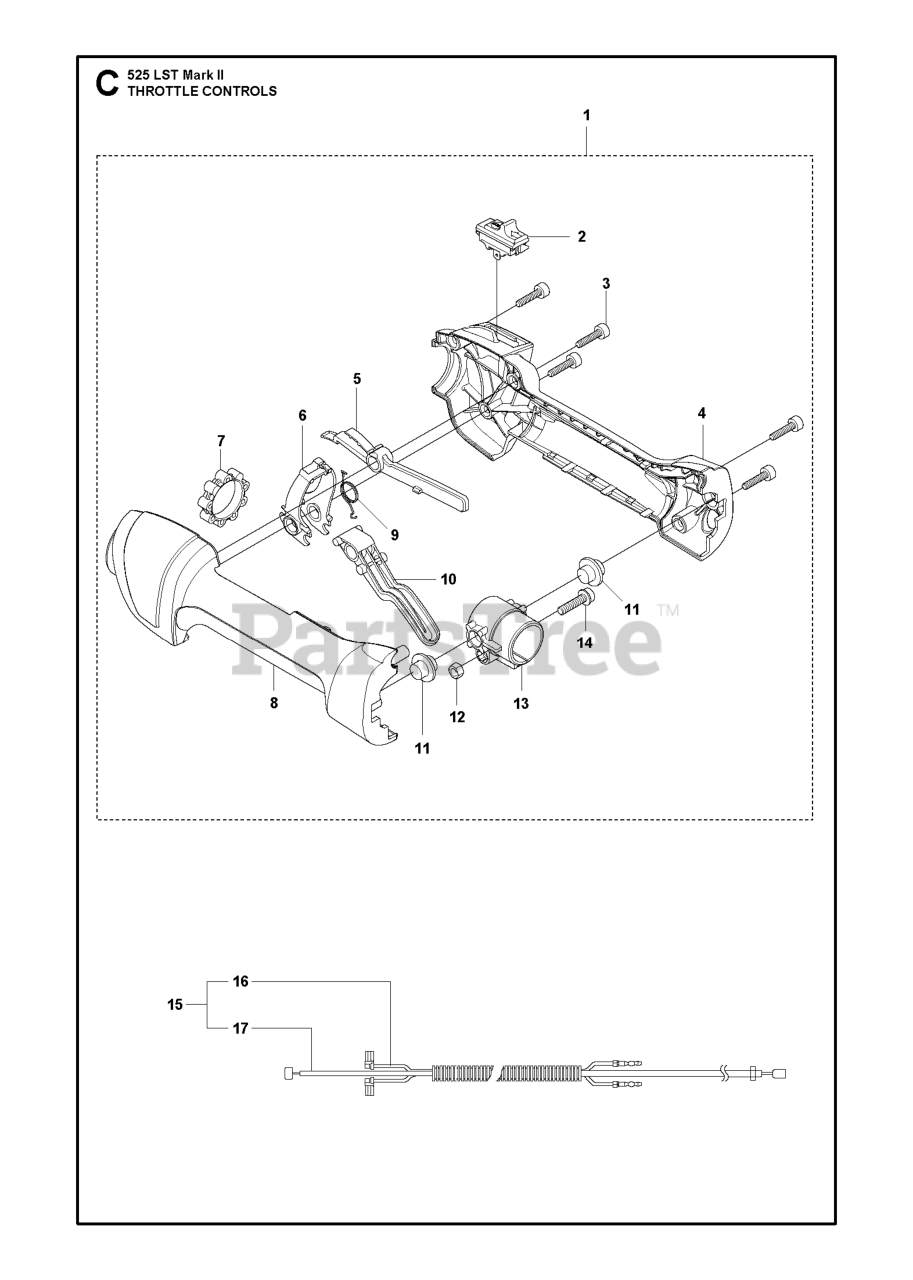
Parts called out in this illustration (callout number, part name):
1	THROTTLE CONTROL
2	STOP BUTTON
5	THROTTLE LOCK
7	VIBRATION DAMPER
9	RETURN SPRING
10	THROTTLE TRIGGER
15	WIRING ASSY
16	SHORT CIRCUIT CABLE
17	THROTTLE CABLE
